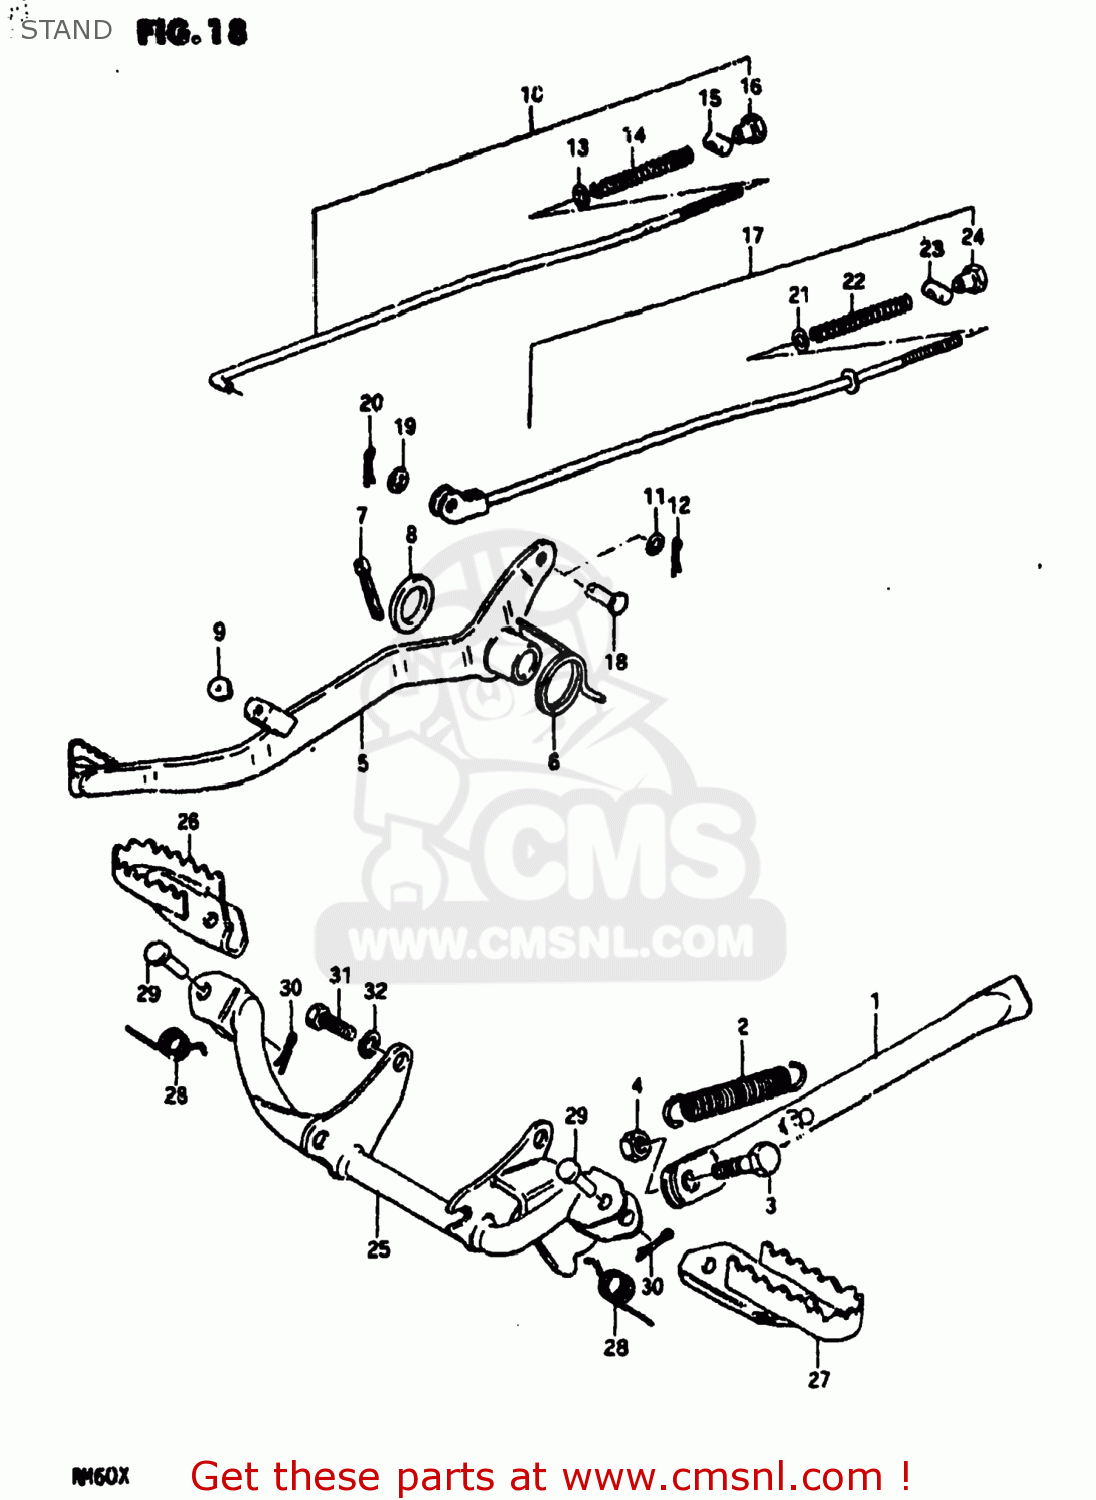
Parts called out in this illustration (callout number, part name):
1	STAND,SIDE
2	SPRING
3	BOLT
4	NUT
5	PEDAL,BRAKE
6	SPRING
7	COTTER PIN
8	WASHER(15.5X26X2.3)
9	STOPPER,BRAKE PEDAL
10	ROD ASSEMBLY,REAR BRAKE
11	WASHER
12	PIN 20X20
13	WASHER
14	SPRING
15	PIN(11X18)
16	NUT
17	ROD ASSEMBLY,REAR BRAKE
18	PIN(L:13.5)
19	WASHER
20	PIN 20X20
21	WASHER
22	SPRING
23	PIN(11X18)
24	NUT
25	BAR,FRONT FOOTREST
26	FOOTREST,FRONT,RIGHT
27	FOOTREST
28	SPRING
29	PIN
30	PIN 20X20
31	BOLT
32	LOCK WASHER
